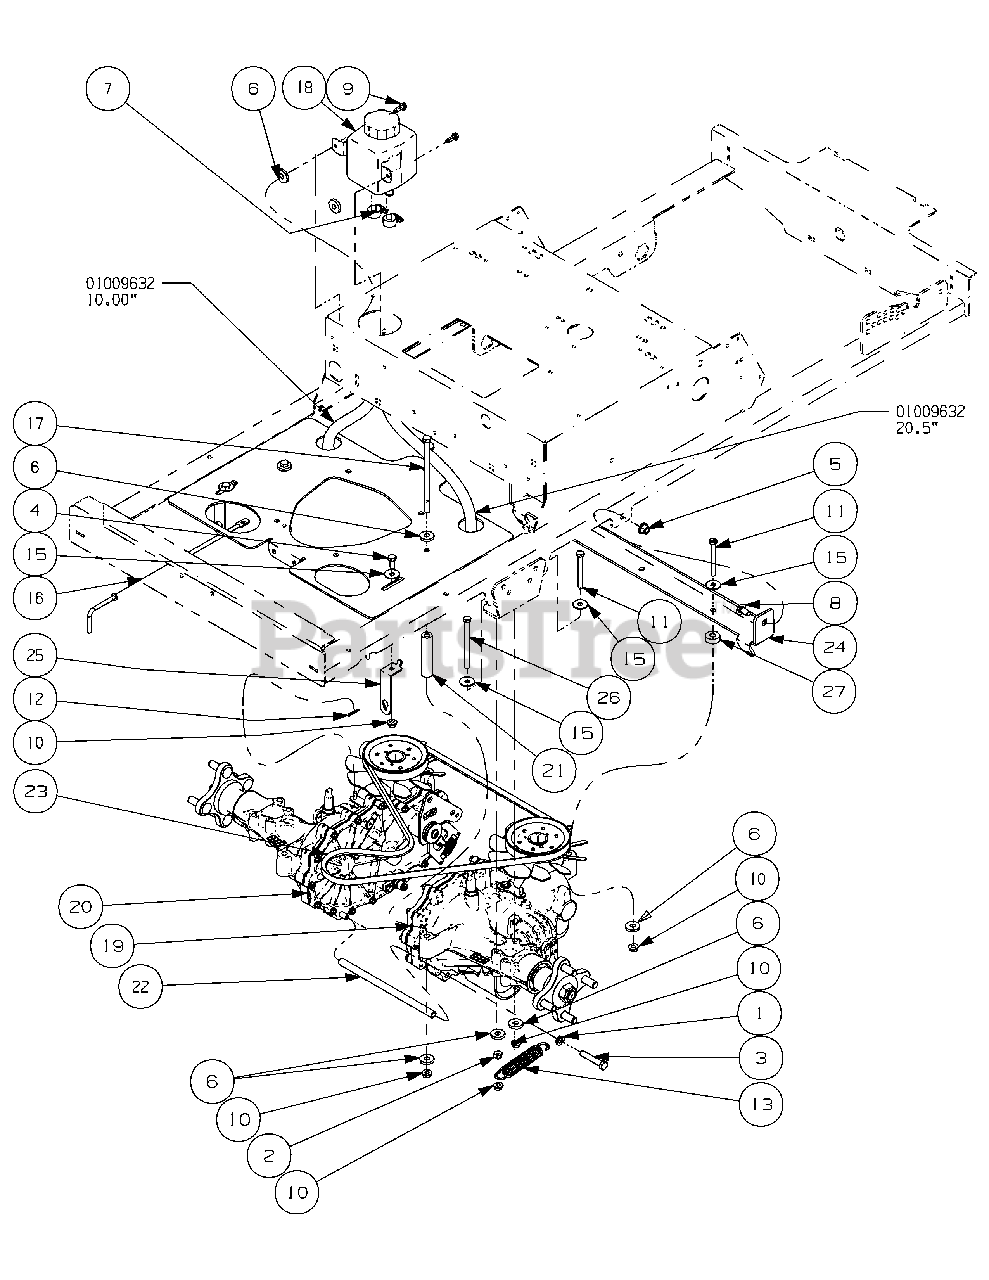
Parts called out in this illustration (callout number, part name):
1	Lock Washer, 3/8 Zinc
2	Nylock Nut, 5/16-18
3	Hex Cap Screw, 3/8-16 x 2.00
4	Hex Cap Screw, 5/16-18 x 3/4
5	Nut, Flange Lock, 3/8-16
6	Idler Washer
7	Hose Clamp
8	Carriage Bolt, 3/8-16
9	Self Tapping Screw, 1/4-20 x .75
10	Nut, Lock, HexFlange, 5/16-18
11	Hex Cap Screw, 5/16-18 x 2.75
12	Cotter Pin, .072 x 1.12 Lg
13	Extension Spring, .865 OD x 4.68 Long
14	Fuel Hose, .50 ID x .75 OD (30.5 in inches)
15	Washer, 5/16 x 1.06
17	Hex Cap Screw, 5/16-18 x 6.00
18	Hydraulic Tank
19	IZT Transmission, Right Hand
20	IZT Transmission, Left Hand
21	Spacer, .375 ID x .75 OD x 3.30
22	Transmission Support Tube
23	V-Belt, 58.4
24	Transmission Front Mounting Bracket
25	Neutral Bracket
26	Bolt, 5/16-18 x 4.00
27	Spacer .406 ID x 1.0 OD
